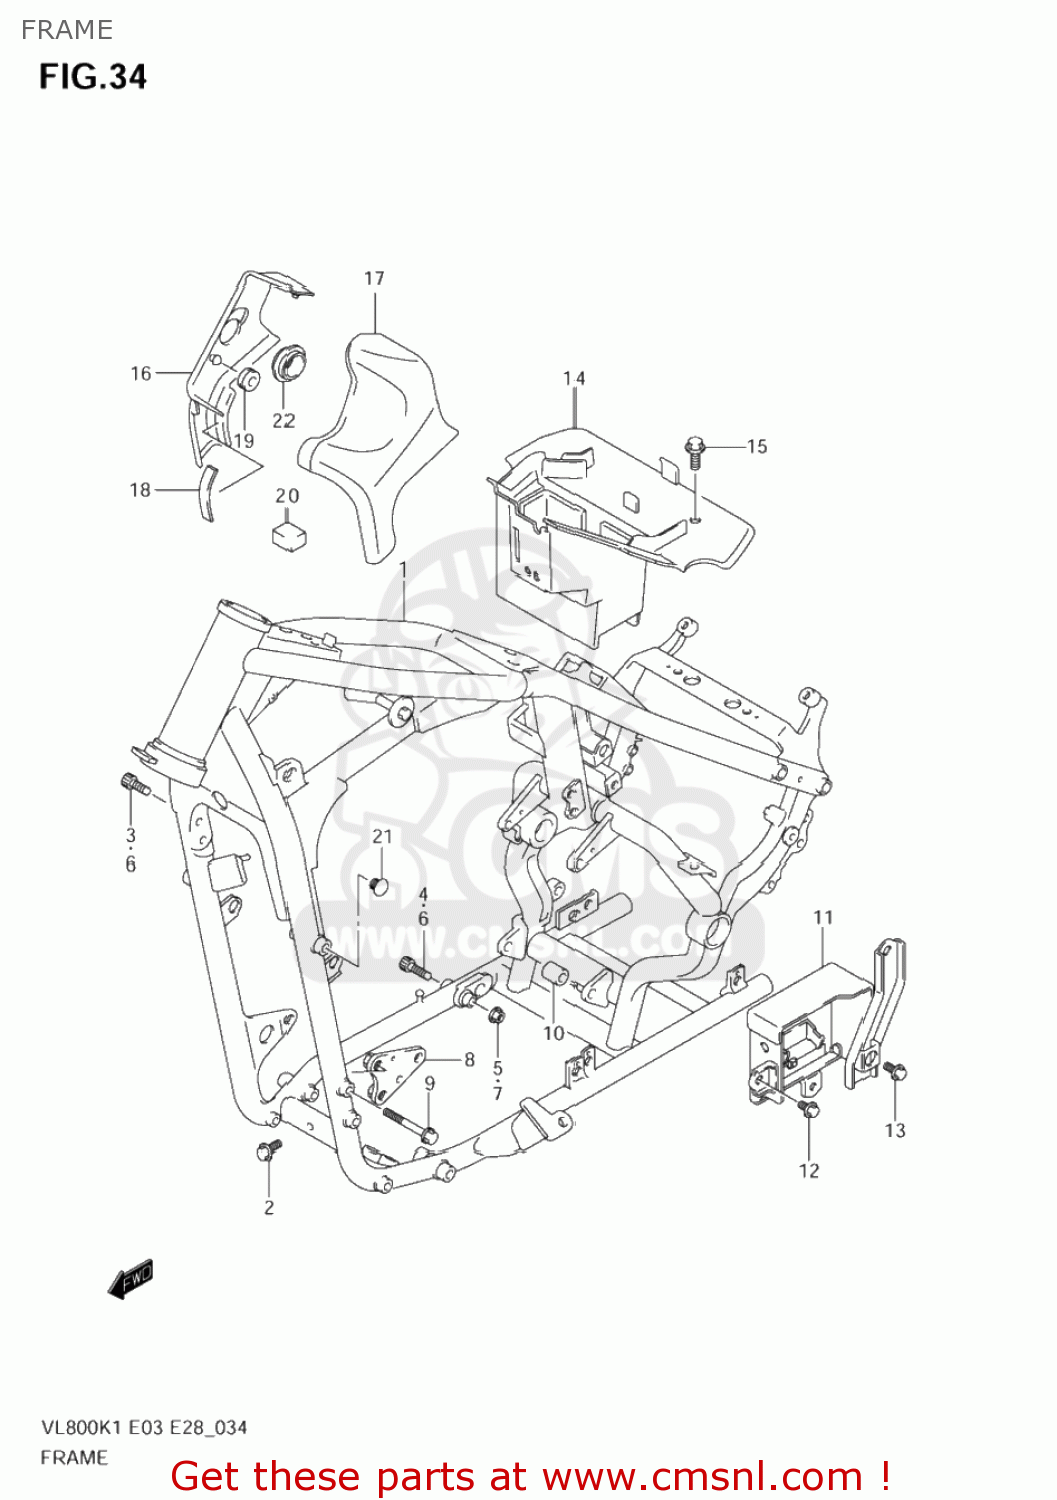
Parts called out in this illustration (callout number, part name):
1	FRAME (BLACK)
2	BOLT
3	BOLT
4	BOLT
5	NUT
6	BOLT
7	NUT
8	PLATE,ENGINE MOUNT NO.1,L
9	BOLT
10	SPACER,ENG MTG LR
11	HOLDER COMP,EL
12	BOLT
13	BOLT
14	HOLDER COMP,EL
15	BOLT(6X16)
16	COVER,FRAME HEAD,R(BLACK)
17	COVER,FRAME HE
18	CUSHION,FR FENDER
19	CUSHION
20	CUSHION
21	CAP(OD:14)
22	CAP
